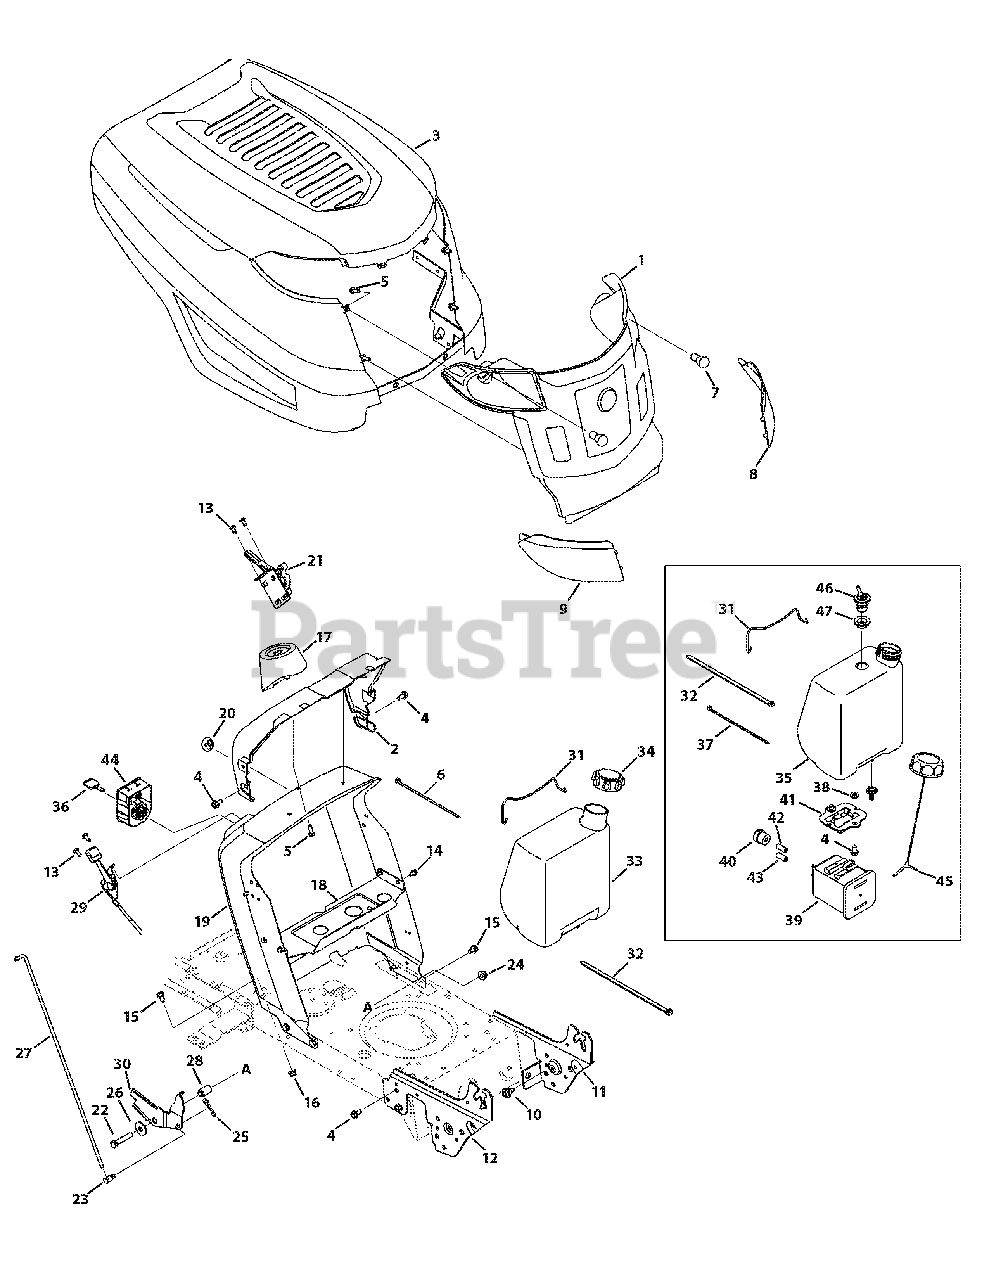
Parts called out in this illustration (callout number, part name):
1	Grill Assembly, Troy-Bilt
1	Grill Assembly, K-Style
2	Dash Collar
2	K-Style Bumper
2	Screw, #12-16 x .50
3	Hood Assembly
4	Screw, 5/16-18 x .750
5	Screw, 1/4-15 x .750
6	Cable Tie
9	Right Lens
10	Shoulder Screw, 5/16-18 x .43 x .29
11	Left Support Pivot Bracket
12	Right Support Pivot Bracket
13	Screw, 1/4-20 x .500
14	Hex Washer Screw, 1/4-20 x .500
15	Screw, 5/16-18 x .625
16	Flangelock Nut, 5/16-18
17	Steering Support
18	Gas Tank Support Bracket
19	Dash, No RMC - Red
20	Choke Plug
21	7-Speed Control Assembly
22	Hex Screw, 3/8-16 x 2.0
23	Ferrule, 1/4-20 x 1.00
24	Flangelock Nut, 3/8-16
25	Bow Tie Cotter Pin, 72
26	Flat Washer, .411 x 1.25 x .100
27	Speed Selector
28	Flange Spacer, .390 x .671 x 1.095
29	Throttle/Choke Cable
31	Battery Assembly Rod
32	Cable Tie
33	1.5 Gallon Fuel Tank
34	Fuel Cap
35	1.36 Gallon Fuel Tank
37	Cable Tie
38	Flat Washer, .344 x .750 x .120
39	5 Gallon Carbon Canister
40	Vent Filter Canister
41	Canister Adapter Bracket
42	Fuel Hose, White
43	Fuel Hose, Yellow
44	3 Position Key Switch
45	Fuel Cap, 2.25"
46	Rollover Valve
47	Rubber Grommet, 23 x 3.55
